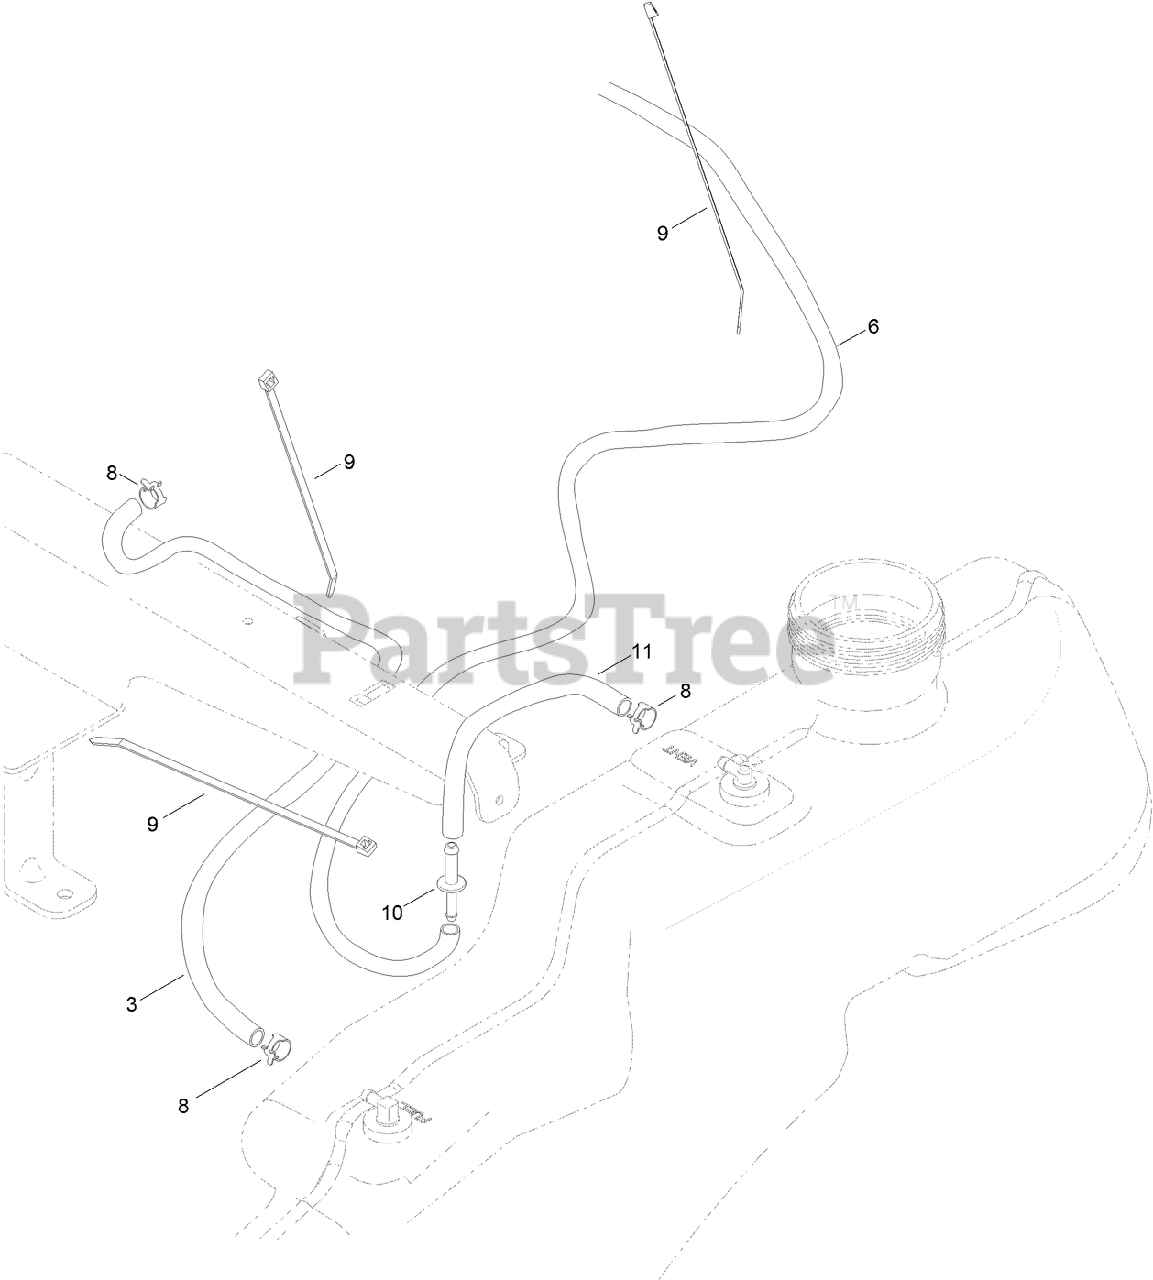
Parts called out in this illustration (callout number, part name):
3	HOSE-FUEL
6	HOSE-FUEL
8	CLAMP-HOSE
9	TIE-CABLE
10	ADAPTOR-ORIFICE
11	HOSE-FUEL
